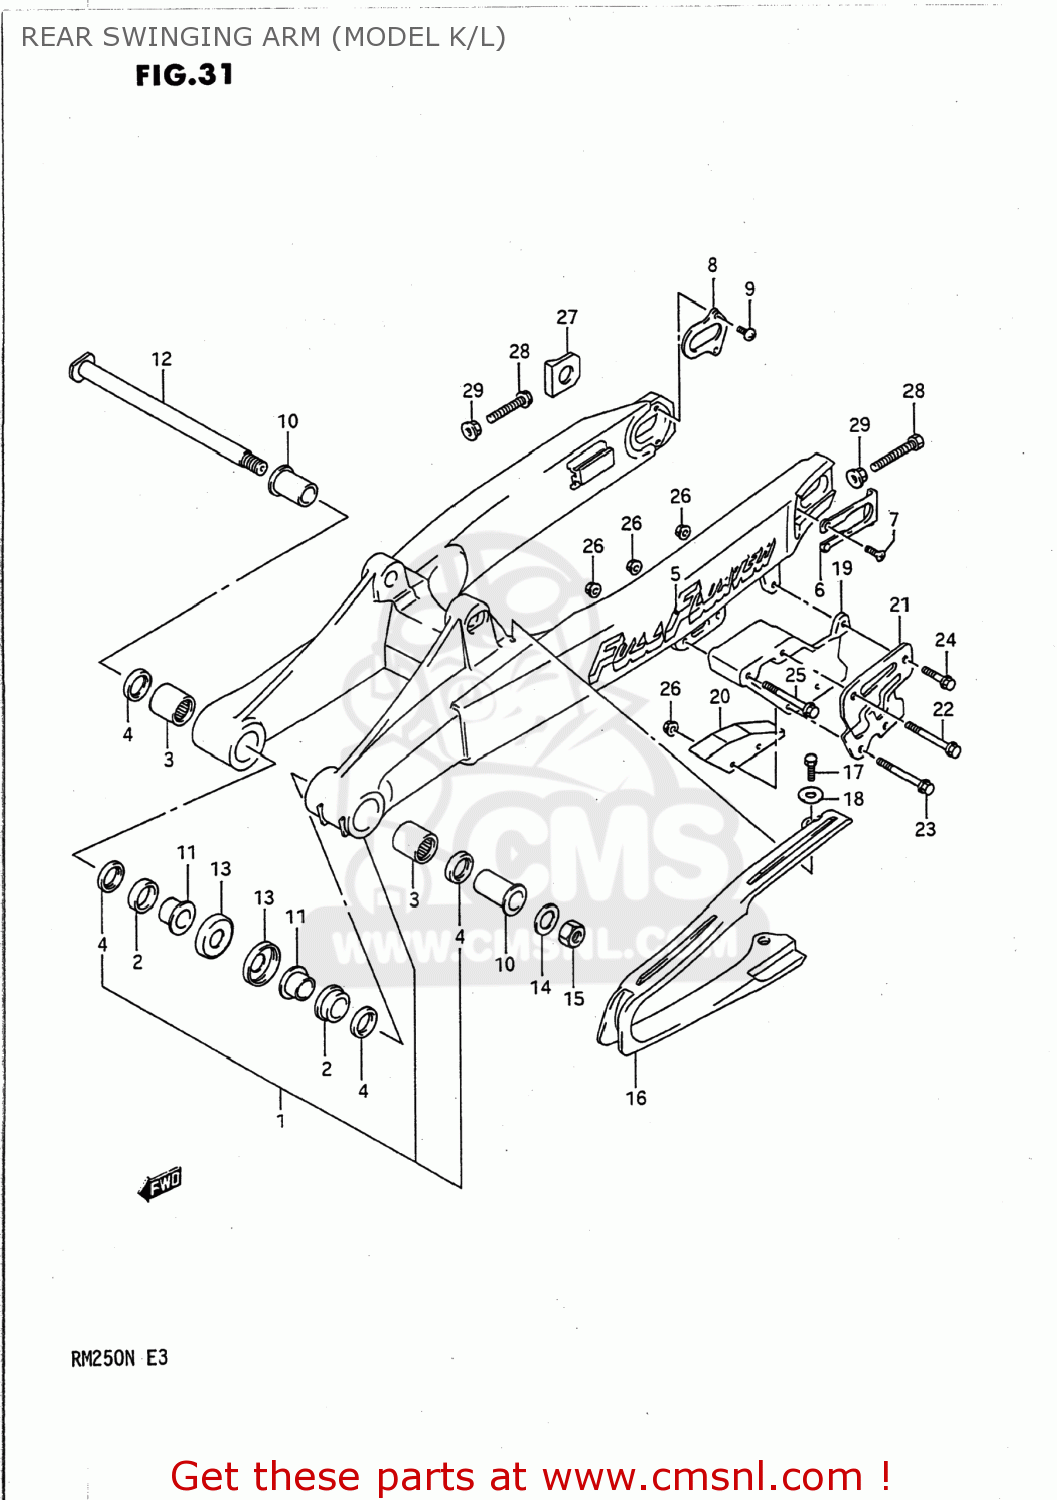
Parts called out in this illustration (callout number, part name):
1	SWING ARM ASSEMBLY,REAR
2	BUSHING,SWGARM PIVOT
3	BEARING(22X29X30)
4	SEAL,OIL(22X29X4)
5	EMBLEM,SWING ARM
6	PLATE,OUTER
7	SCREW(5X10)
8	PLATE,INNER
9	SCREW (5X8)
10	SPACER,REAR SWING ARM
11	SPACER,SWGARM PIVOT INNER
12	SHAFT,RR SWINGINGARM PIVOT
13	COVER,SWINGINGARM PIVOT
14	WASHER
15	NUT
16	BUFFER,CHAIN TOUCH DEFENSE
17	BOLT
18	WASHER
19	GUIDE,CHAIN
20	DEFENSE,CHAIN GUIDE
21	PLATE,CHAIN GUIDE OUTER
22	BOLT
23	BOLT
24	BOLT
25	BOLT
26	NUT
27	WASHER,CHAIN ADJUSTER
28	BOLT
29	NUT
